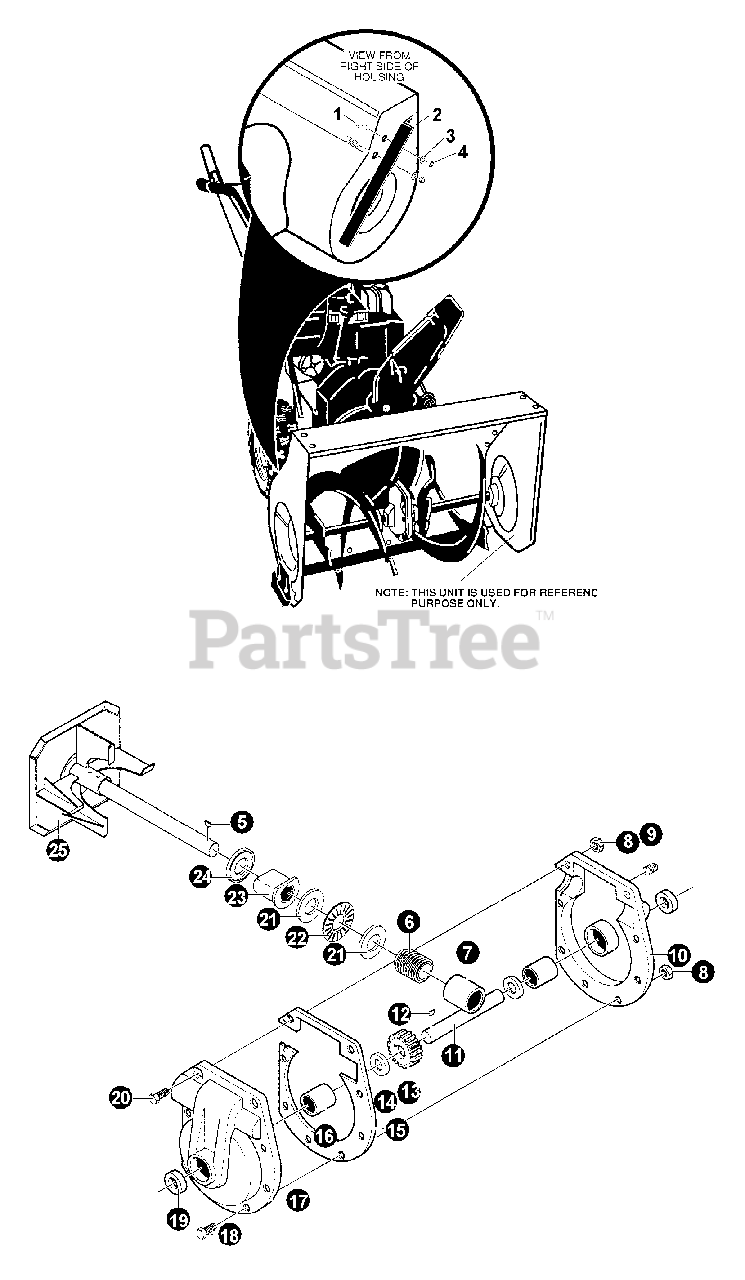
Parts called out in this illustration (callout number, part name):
1	BOLT - 5/16-18 X 3/4"
2	BAR, DRIFT CUTTER
3	LOCKWASHER
4	NUT - 5/16-18
5	KEY, HI-PRO 606 .75DIAX.187WD
6	GEAR - WORM
7	BEARING, SLEEVE
8	NUT - 5/16-24
9	PLUG
10	CASE, GEAR - LEFT
11	SHAFT, AUGER OUTPUT
13	GEAR - WORM
14	WASHER
15	GASKET, GEAR BOX
16	BEARING, SLEEVE
17	CASE, GEAR - RIGHT
18	SCREW - 5/16-24 X 1"
19	SEAL, OIL
20	SCREW - 5/16-24 X 1-1/2"
21	WASHER - .752X1.24X.093
22	BEARING, ROLLER
23	BEARING, FLANGE
24	RING, QUAD
25	IMPELLER ASSY
